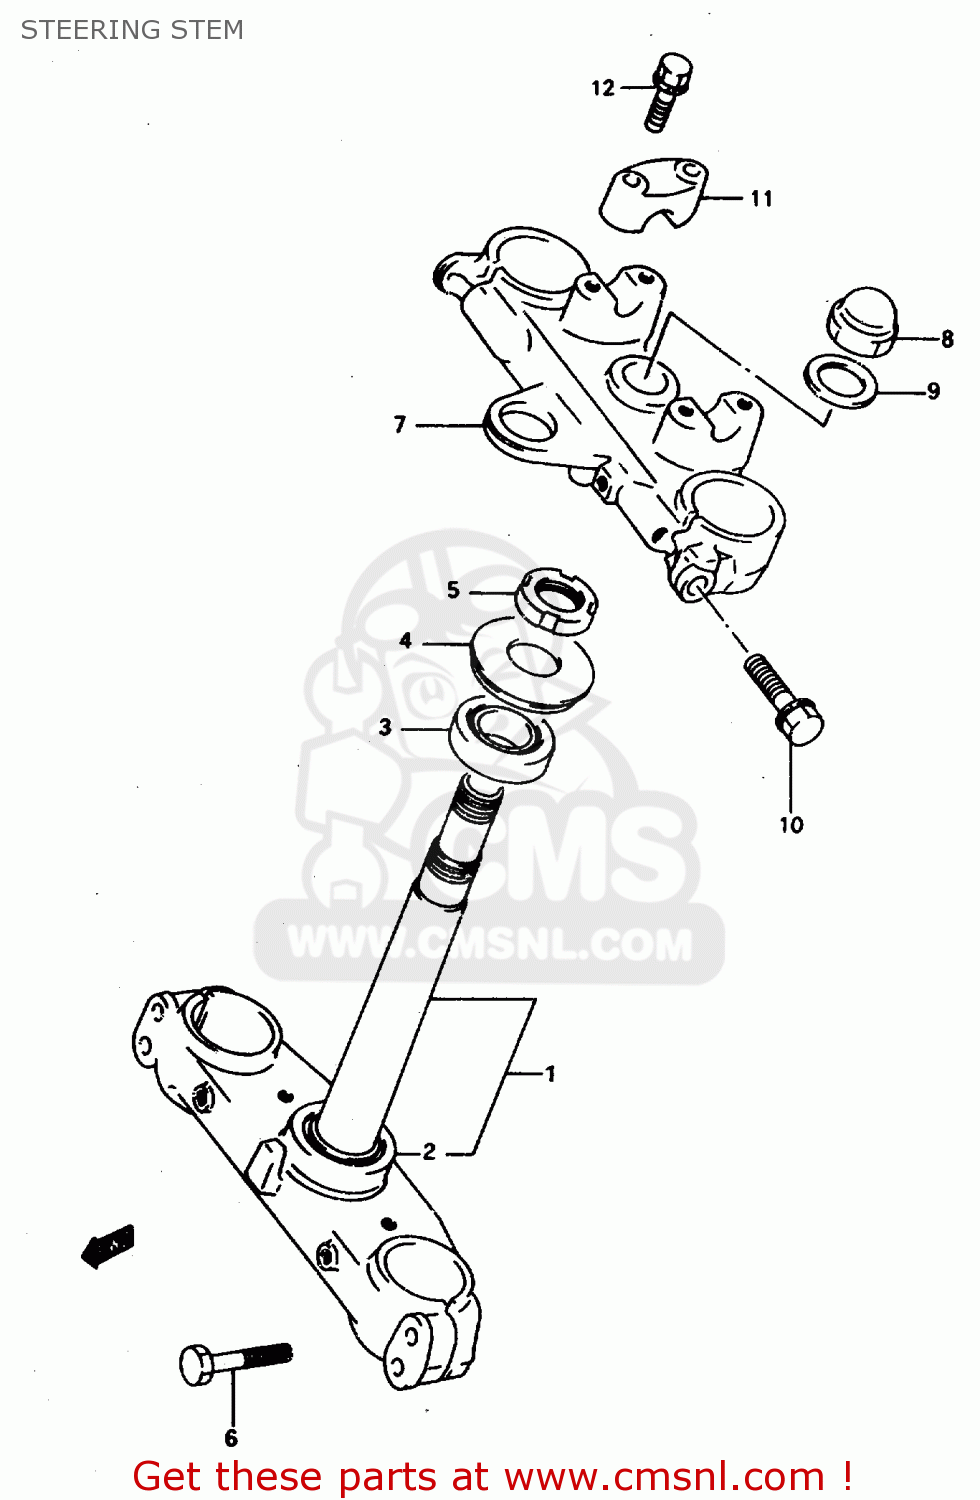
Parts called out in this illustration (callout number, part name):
1	STEM,STEERING
2	BEARING(30X55X17)
3	BEARING(25X47X15)
4	SEAL,STEERING UPR DUST
5	NUT,STEERING STEM
6	BOLT,STEM(8X50)
7	HEAD,STEERING STEM
8	NUT,CAP
9	WASHER(22.5X32X1.6)
10	BOLT, UPPER BRACKET
11	HOLDER,HANDLE UPR
12	BOLT
